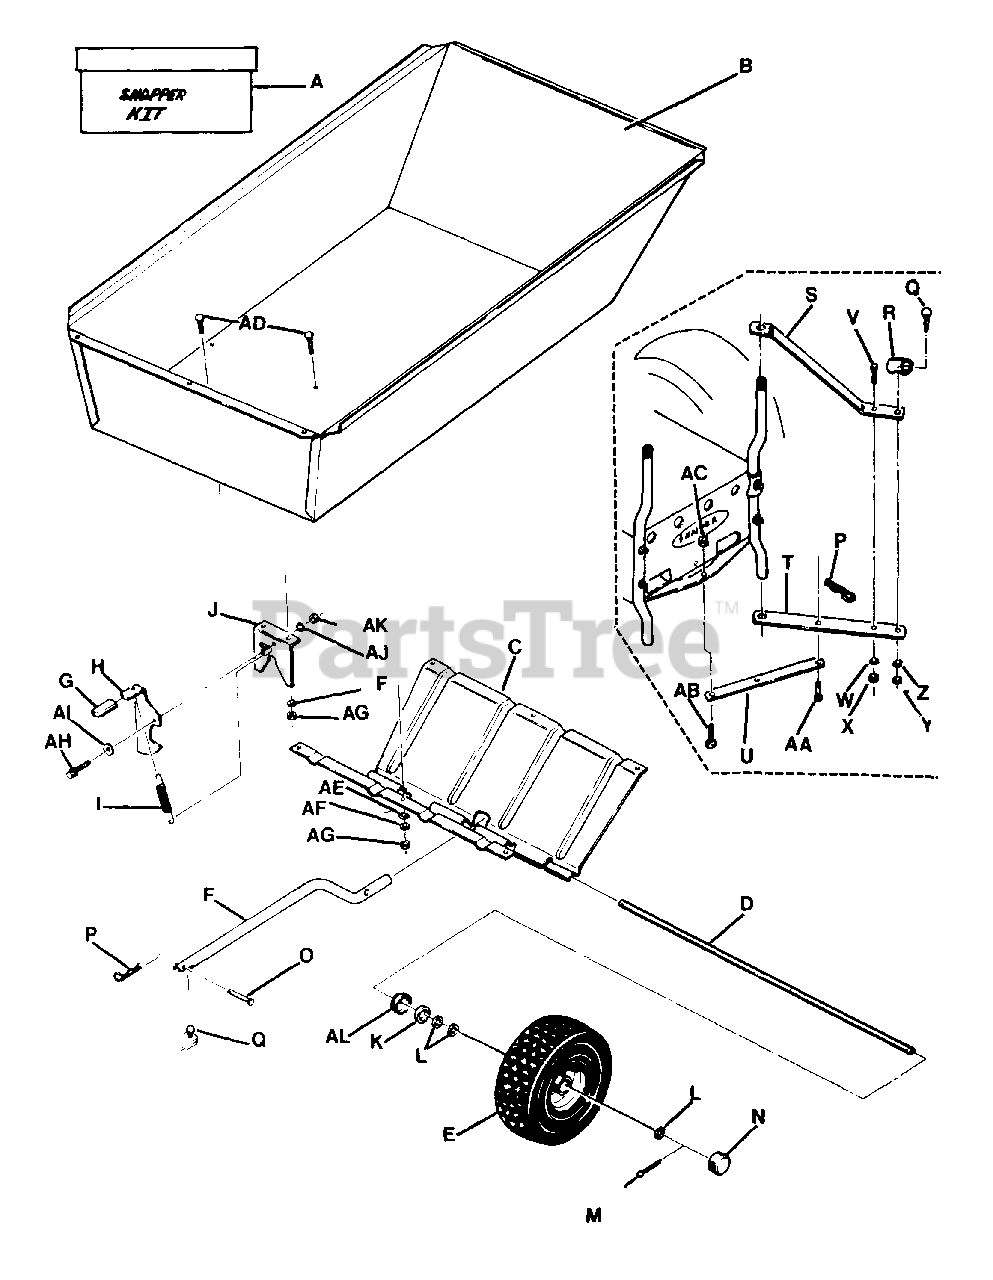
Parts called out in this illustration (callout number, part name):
A	KIT, SNAPPER WAGON
B	BODY, WAGON CART
C	SUPPORT, AXLE
D	AXLE
E	ASSEMBLY, Tire & Rim
F	TONGUE
G	GRIP, LATCH
J	YOKE
K	WASHER, FELT
L	WASHER
M	COTTER-PIN, 5/32 x 1
N	HUB-CAP
O	PIN, 3/8 CLEVIS
P	PIN, HAIR
Q	BALL, HITCH
R	COLLAR, HITCH
S	BAR, UPPER DRAW
T	BRACE, DRAW BAR
U	BAR, LOWER DRAW
V	SCREW, HEX HEAD CAP 3/8-24x1
W	WASHER, 3/8 SPLIT LOCK
X	NUT 3/8-24 HEX
Y	WASHER, 7/16 SPLIT LOCK
Z	NUT, 7/16-20 HEX
AA	PIN, HITCH CLEVIS
AB	SCREW, HEX HEAD CAP 1/2-20x1
AC	NUT, 1/2-20 HEX LOCK
AD	BOLT, CARRIAGE 1/4-20x3/4
AE	RETAINER, 1/4 BOLT
AF	WASHER, 1/4 INTERNAL TOOTH LOCK
AG	NUT, 1/4-20 HEX
AH	BOLT, SHOULDER 5/16-18
AI	WASHER, SPRING
AJ	WASHER 5/16 SPLIT LOCK
AK	NUT, 5/16-18 HEX
AL	DUST-CAP
